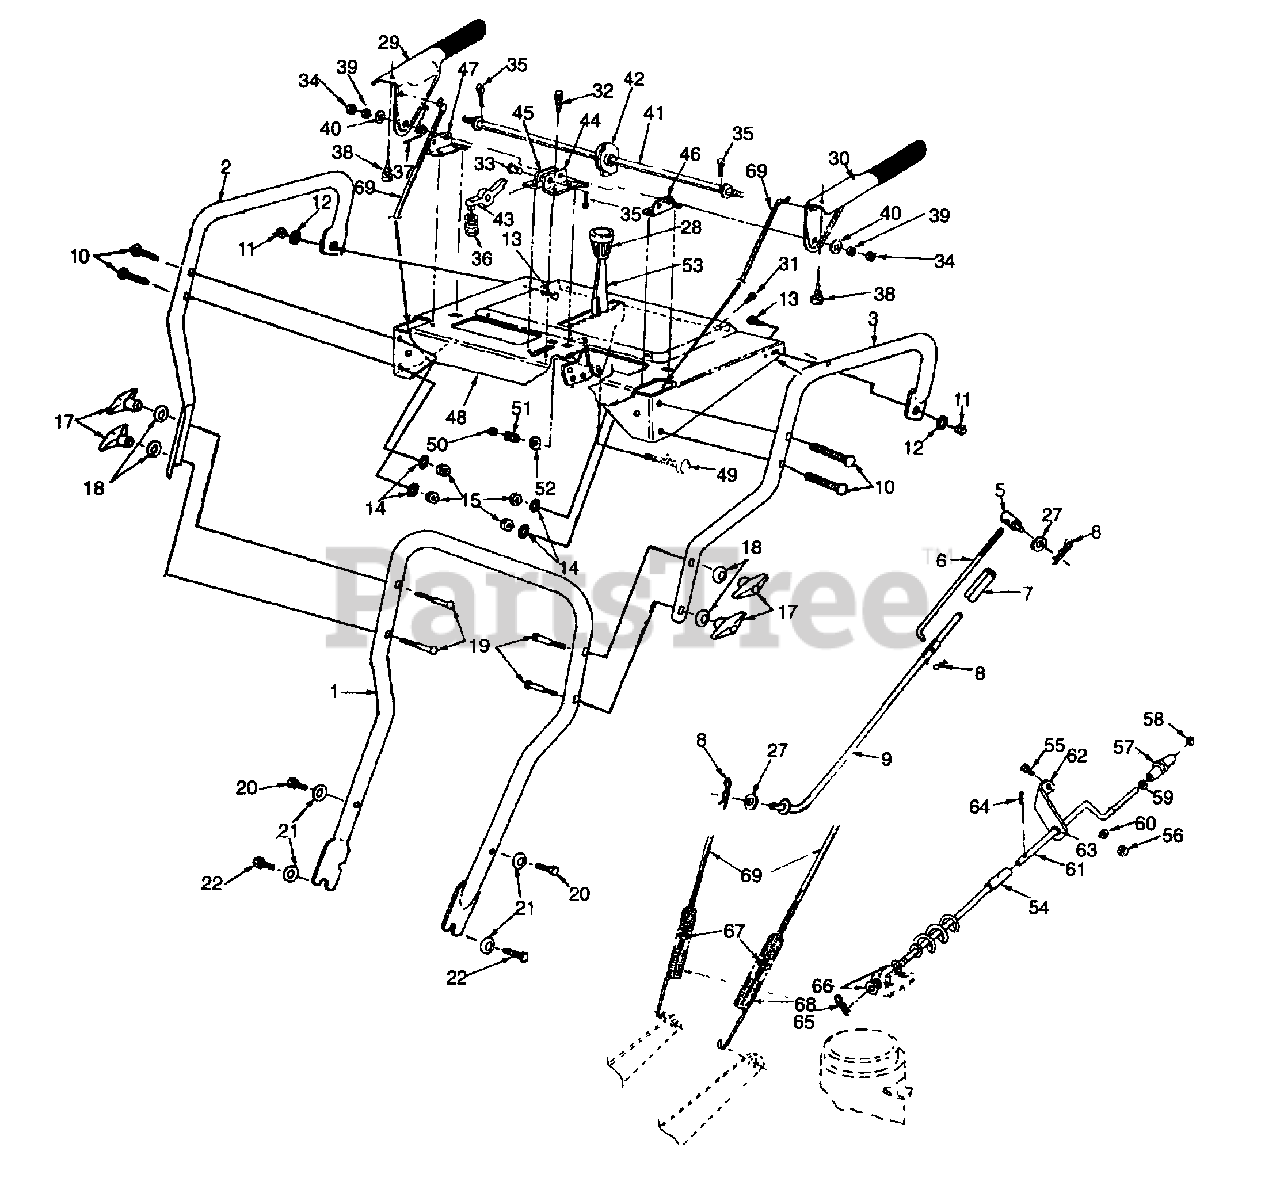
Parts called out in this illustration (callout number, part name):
5	Adjustment Ferrule
6	Upper Shift Rod 5/16 x 9.0
7	2 PC Shift Rod Connector
8	Inter cot-pin 5/16 dia
9	Rod Shift LWR 3/8 x 14.75
10	Carriage Bolt 5/16- 18 x 1.75
11	Hex Nut 1/4 - 20
12	Bell Wash .26 ID x .75 OD x .06T
13	Screw Hex Cap 1/4 -20 X . 75 GR 2
14	Lock Washer 5/16
15	Hex Nut 5/16 - 18
17	Wing nut
18	Bell Wash .345 ID x .88 OD x .060
19	Carriage Bolt 5/16 - 18 x 2.5
20	Hex Scr 3/8 - 16 x 1.75
21	Bell Wash .40 ID x .88 OD x .06
22	Hex Scr 3/8 - 16 x .75
27	FL-Wash SAE .34 x .68 x .062
28	SML shift knob 1.6 DIA sentar
29	Engage Handle Le Blk Dip Rh
30	Engage Handle Lf Blk Dip Lh
31	Pan Head B-tapp Scr #10 X .5
32	Hwhd Sf-tap Scr 1/4-20 X 1/2 zn
33	Clevis Pin .31 Dia X 1.0
34	Nut Hex 5/16-18 Gd 5
35	Cot-pin 3/32 Dia X 1.0
36	Comp Spring .36 Dia X 1.0 Lg
37	Spring Torsion .44 ID
38	Rubber Bumper .63 Dia
39	Lock Washer 5/16
40	Washer Spcl. .345 Sq. X .72 OD
41	Cam Rod
42	Clutch Lock Cam
43	Clutch Lock Pawl
50	Hex Ins L-nut 3/8-24
51	Compression Spring .39 ID X .88
52	Bell Wash .40 ID X .88 OD X .06
56	Hex Nut 1/4-20
57	Chute Crank Knob Countersink
58	Push Cap 3/8 Palnut #375011
59	Flat Washer .38 ID X .60 OD X .033
60	Bell Wash .26 ID X .75 OD X .06t
63	Plastic Bushing .380 ID
64	Internal Cot-pin 1/2 Dia
65	Inter cot-pin 5/16 dia
66	Fl-wash .406 ID X .74 OD X .063
67	Hex Ins L-nut 1/4-20
68	Extension Spring
69	Cbl Clutch Drv
